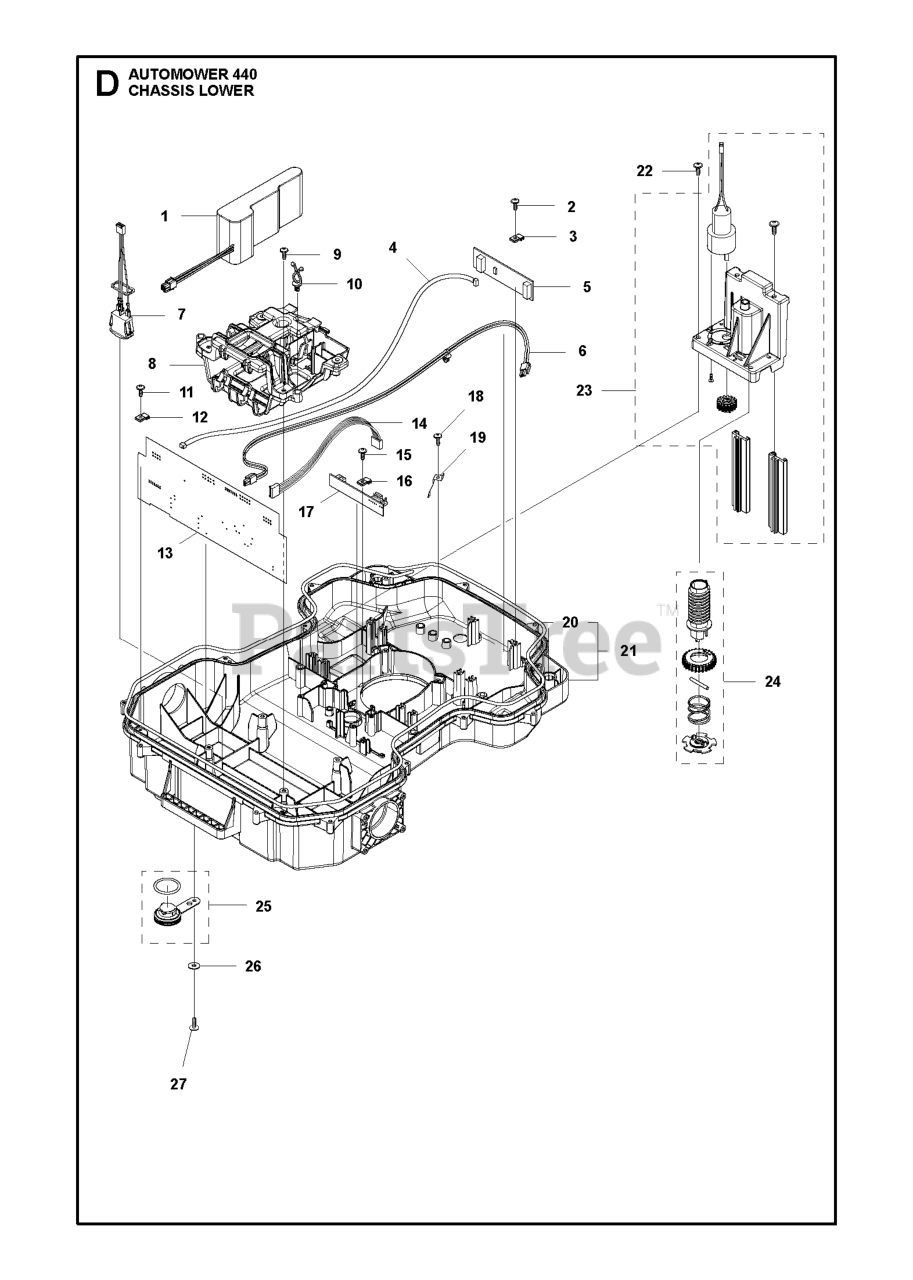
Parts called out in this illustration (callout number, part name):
1	BATTERY 588146401 PACKED
2	SCREW 14MM
3	CLAMP PCB
4	LOOM LOOP SENSOR
5	PRINTED CIRCUIT ASSY LOOP SENS
6	LOOM CHARGING LINK HIGH CHARGI
7	LOOM ON/ OFF
8	HOLDER BATTERY
9	SCREW ITXPANT
10	HOLDER TWIST LOCK
11	SCREW 14MM
12	CLAMP PCB
13	PRINTED CIRCUIT ASSY PCBA MAIN
14	LOOM HEIGHT ADJUSTMENT
15	SCREW 14MM
16	CLAMP PCB
17	PRINTED CIRCUIT ASSY PCBA CUTT
18	SCREW 14MM
19	SPRING GUIDE HEIGHT ADJUSTMENT
20	SEALING STRIP
22	SCREW 14MM
23	MOTOR ASSY HEIGHT MOTOR
24	SCREW KIT
25	PLUG KIT
26	WASHER
27	SCREW ITXPANT
